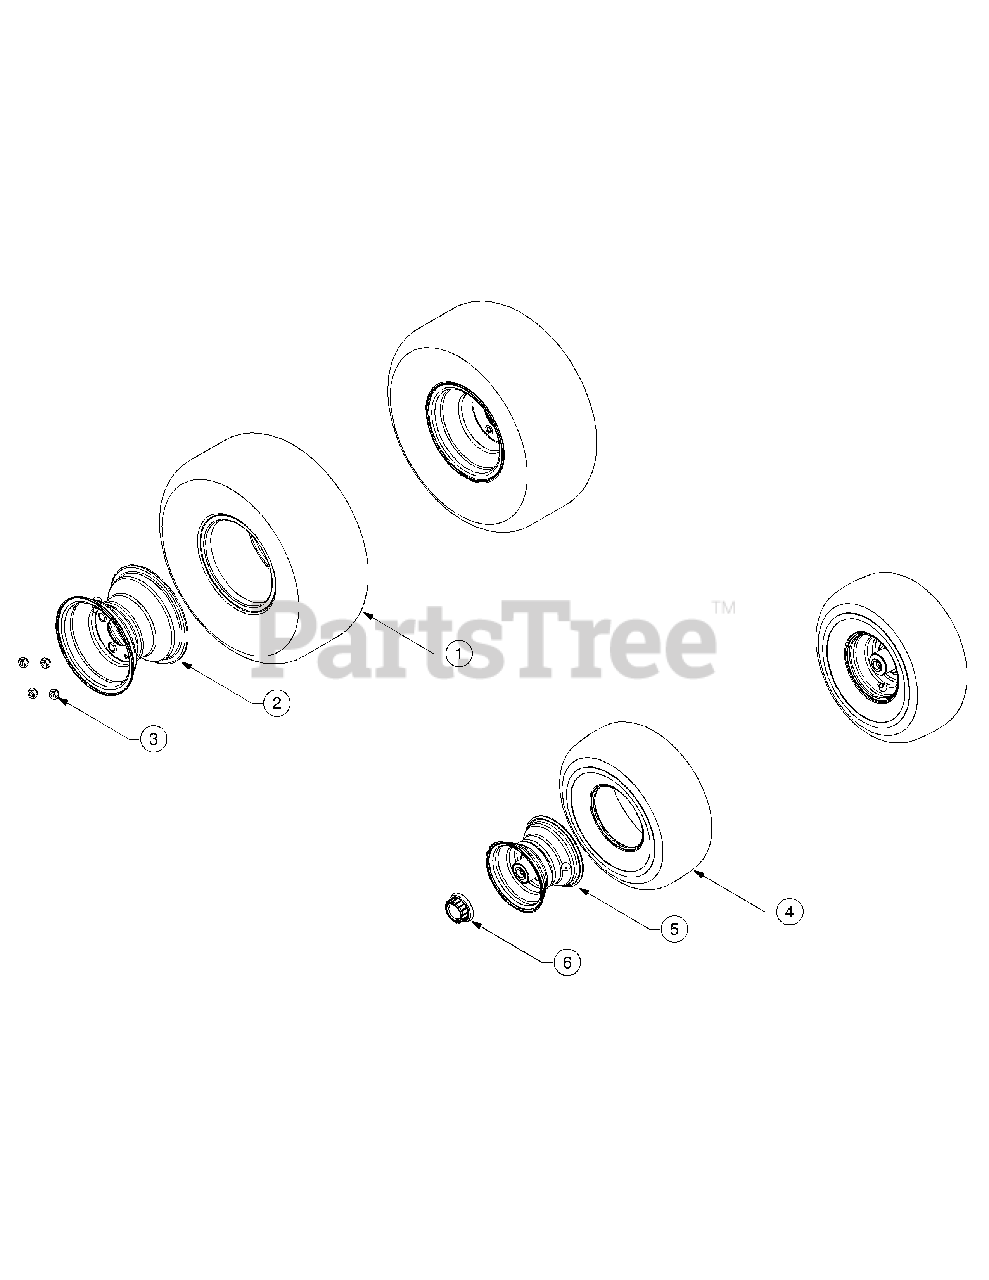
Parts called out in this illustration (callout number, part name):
1	Tire, Turf, Cub Cadet 20 x 10 x 8
3	Lug Nut, 7/16-14
4	Tire, Turf, Cub Cadet 15 x 6 x 6
6	Hub Cap
